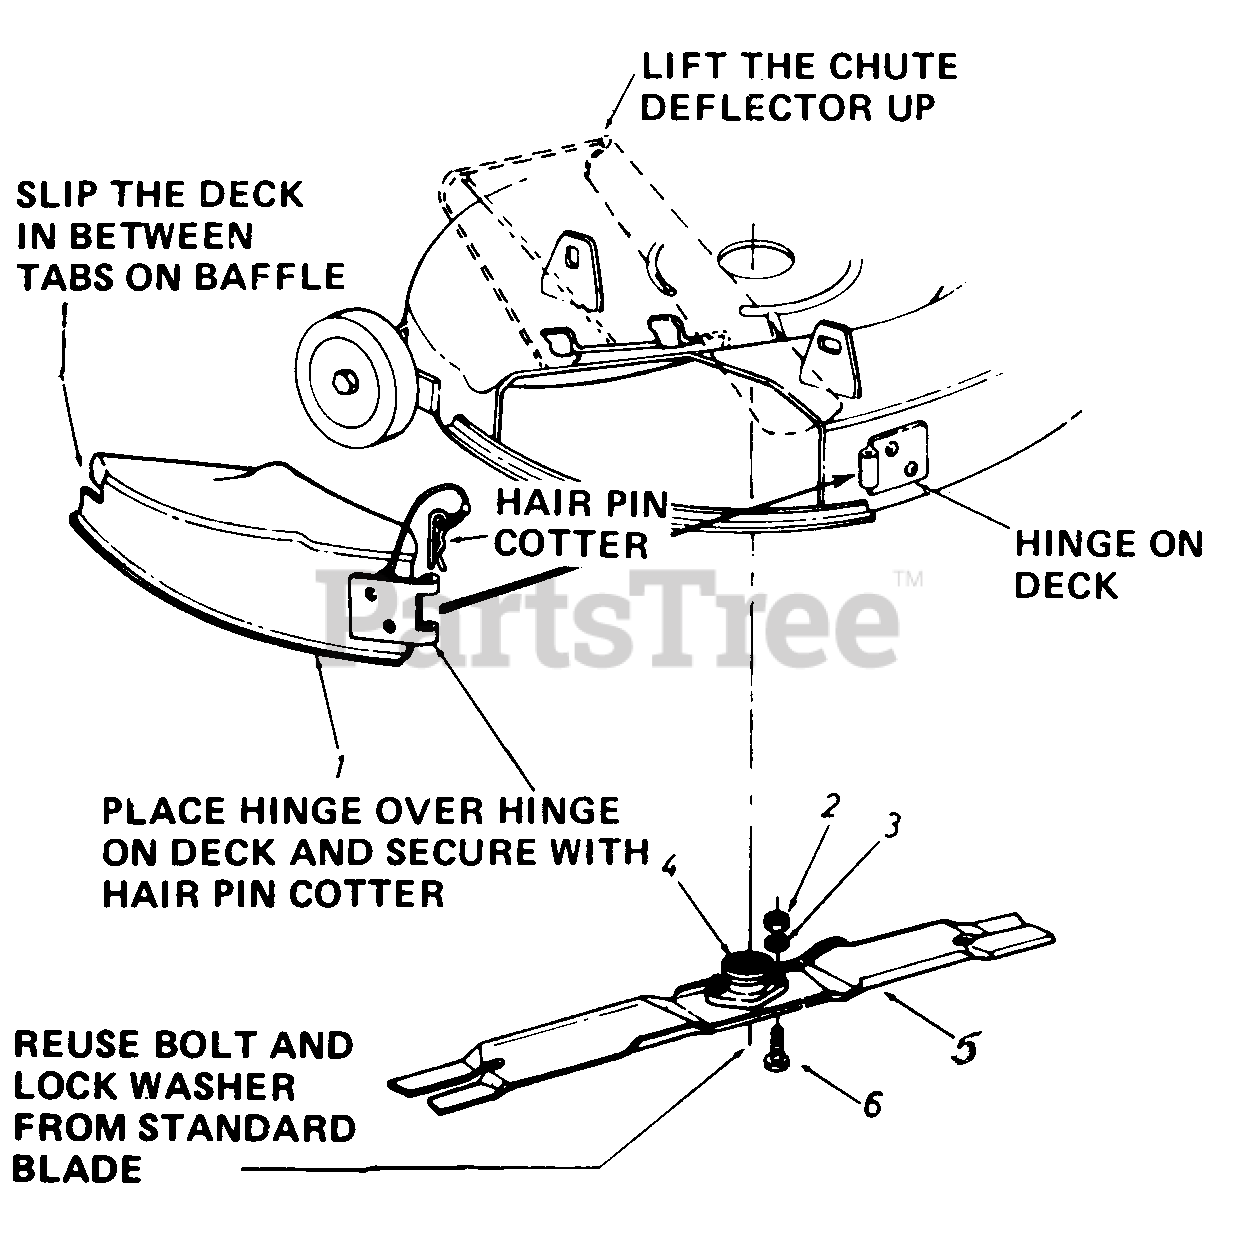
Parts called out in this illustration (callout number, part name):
1	30" Mulching Baffle Ass'y.
2	Hex Nut 5/16-24 Thd.*
3	L.-Wash. 5/16" I.D. *
4	Kit-Blade Adapter Ass'y.
5	30" Mulching Blade
6	Hex Bolt 5/16-24 x 1.0" Lg.H.T.
